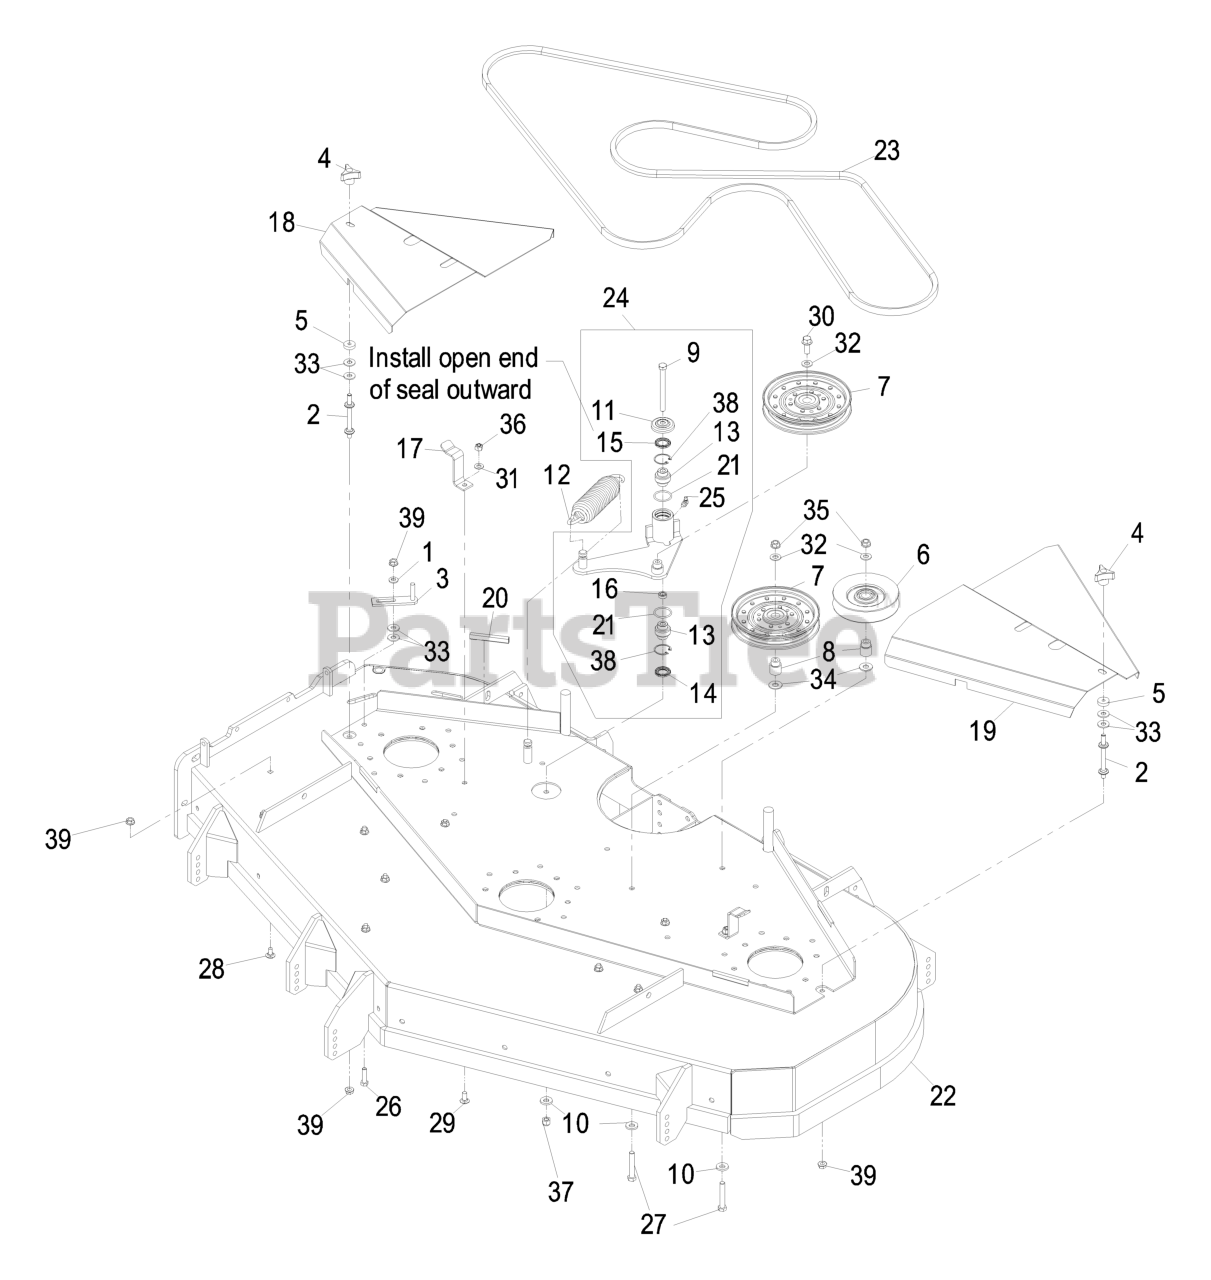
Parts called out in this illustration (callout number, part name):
1	WASHER-SPRING
2	STUD-SHIELD, BELT (SHORT)
3	GUIDE-BELT
4	KNOB-3 PRONG
6	PULLEY-IDLER
8	BUSHING-IDLER
9	SCREW-HH
10	WASHER-BELLEVILLE
11	GUARD-TOP
13	BEARING-SPHERICAL
14	SEAL-LIP, DOUBLE
15	SEAL-LIP, SINGLE
17	LATCH,BELT SHIELD
18	SHIELD, BELT RH 605 W/DEC
19	SHIELD, BELT LH 605 W/DEC
20	STRIP-SEAL
22	ASM, DECK 605 W/DECALS
23	BELT,BLADE DRIVE
24	KIT, IDLER ARM W/BEARINGS
25	FITTING-GREASE, 90 DEG
26	SCREW-HH
27	SCREW-HH
28	SCREW-CARR
29	SCREW-CARR
30	SCREW-HHF
31	WASHER-PLAIN
32	WASHER-FLAT
33	WASHER-FLAT
34	WASHER-FLAT
35	NUT-HHF, WHIZ
36	NUT-LOCK, NI
37	NUT-LOCK, NI
38	RING-SNAP
40	Asm, Deck Complete 60"
